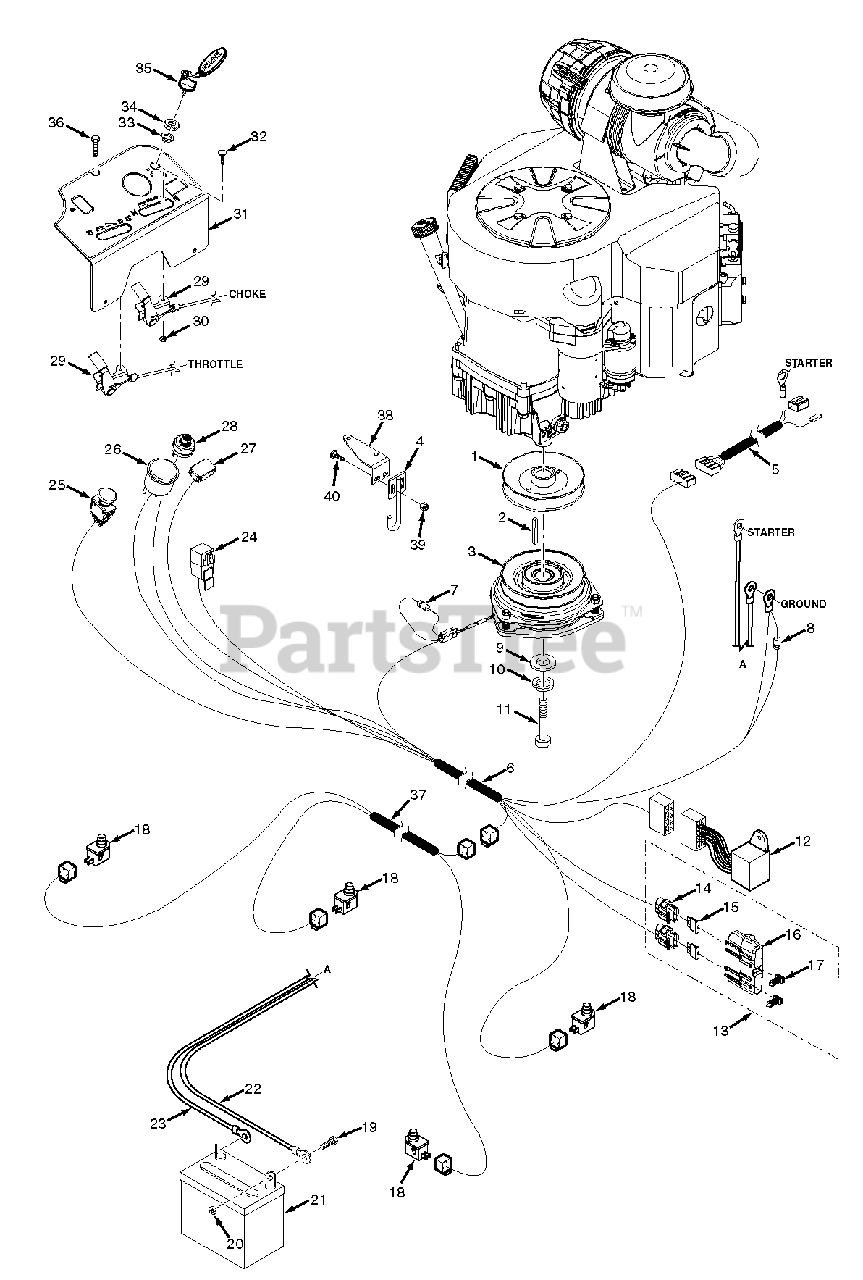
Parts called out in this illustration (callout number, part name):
1	Pulley, 5.80 Dia. - 1.125 Bore
2	Key, 1/4 x 1/4 x 3-1/4"
3	Electric Clutch w/Tag (GT-3.5)
3	Electric Clutch w/Tag (GT-5) - 72V
4	Weldment, Anti-Rotation
5	Wire Harness Adapter, Kawasaki
5	Wire Harness Adapter, Briggs & Stratton
5	Wire Harness Adapter, Kohler
6	Wire Harness, SCZ
7	Diode, 600V - 6A
8	Diode
9	Flatwasher, 7/16-.469 x 1.75 x .25
10	Lockwasher, 7/16" Spring
11	Bolt, Hex Head 7/16-20 x 2-1/4" w/Patch (Kawasaki)
11	Bolt, Hex Head (Briggs & Stratton)
12	Electric Module
13	Double Fuse Assembky
14	Fuse Holder
15	Fuse, 20 Amp
16	Cover, Sealed Double
17	Clip, Wire
18	Switch, N.O.
19	Bolt, Hex Head 1/4-20 x 1/2"
20	Nut, 1/4-20
21	Battery
22	Battery Cable, 27" Black
22	Battery Cable, 18" Black (Kohler)
23	Battery Cable, 25" Red
24	Relay
25	Switch, PTO - 10 Amp
26	Ammeter
27	Hourmeter
28	Keyswitch w/Hardware
29	Control Cable (Kawasaki, Kohler Choke Cable)
29	Control Cable (Briggs & Stratton)
29	Control Cable (Kohler Throttle Cable)
30	Nut, Elastic Stop #10-24
31	Instrument Panel w/Decal
32	Bolt, Carriage #10-24 x 1/2"
33	Lockwasher, 5/8" Internal
34	Nut, Hex 5/8-32
35	Key, Ignition
35	Key Assembly w/Fob
36	Bolt, Hex Head 1/4-20 x 1/2" Serrated Flange
37	Wire Harness, Operator Platform -SCZ
38	Bracket, Anti-Rotation
39	Nut, FLF HH Elastic Stop 5/16-18
40	Bolt, Carriage 5/16-18 x 1"
